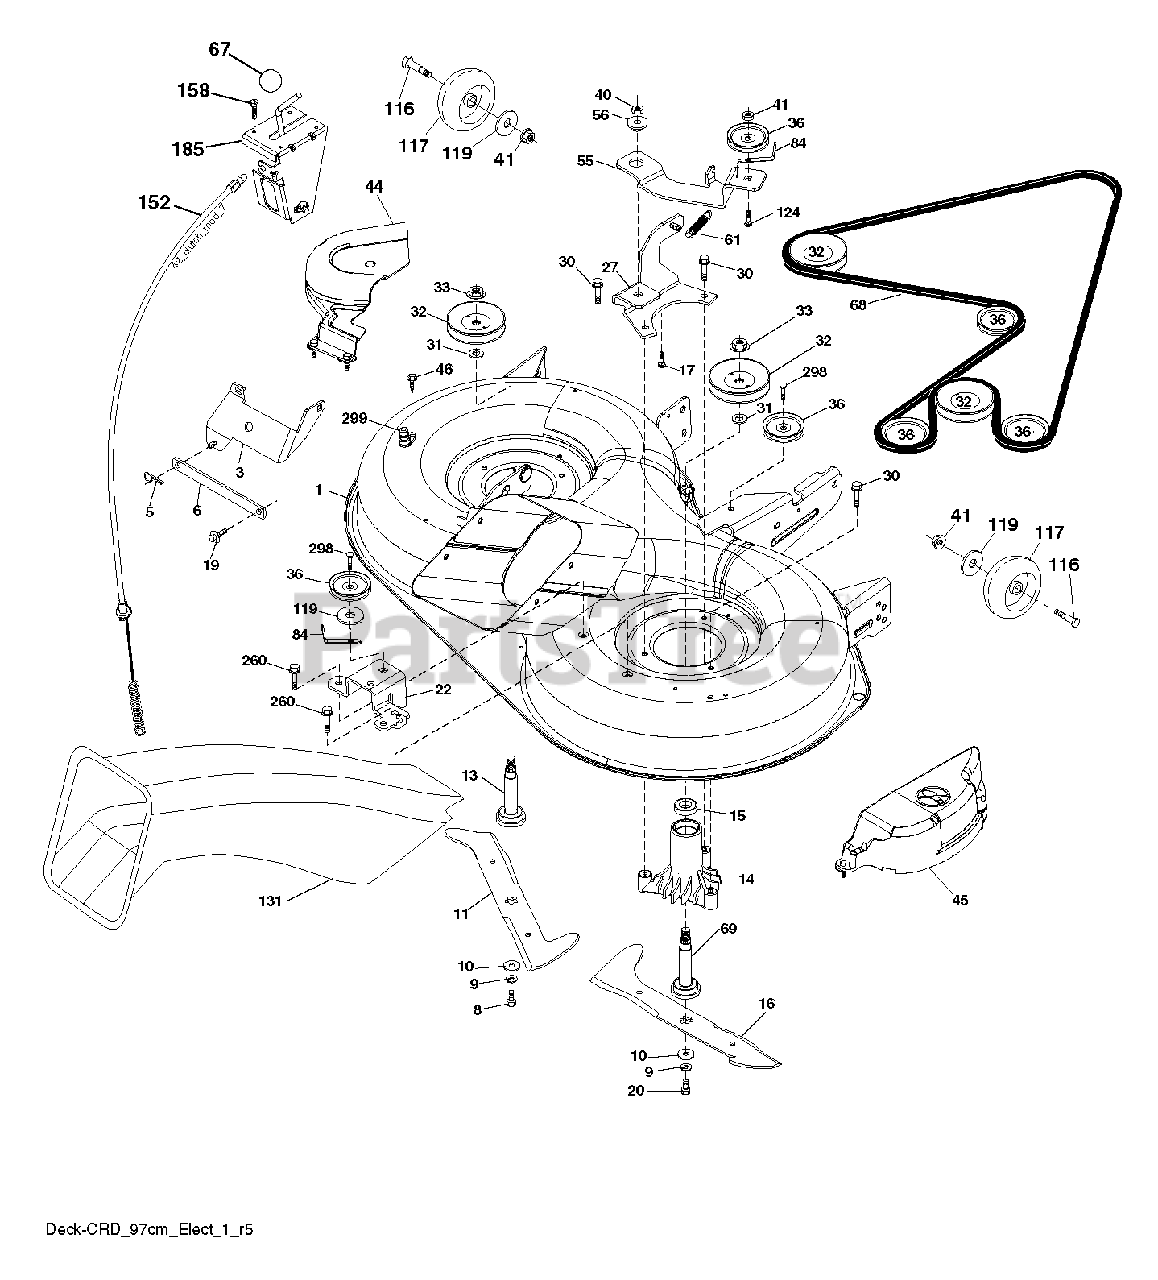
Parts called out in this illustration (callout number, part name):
3	BRACKET.ASM.BAR.SWAY.CHASS
5	RETAINER-SPRNG RB
6	BAR SWAY
9	LOCKWASHER
10	WASHER.BLADE
11	BLADE.3N1.LH.CRD.97
13	SHAFT ASM VENT
14	HSG MANDREL
16	BLADE.3N1.RH.CRD.97
17	BOLT.3/8-14X1.25
19	BOLT SHD 5/16-18
22	BRACKET.SUPT.IDLER.REAR.RH
27	BRACKET.ASM.SUSP.REAR.RH.
30	SCREW, WASHER HEAD
31	WASHER.SPACER.MANDREL
32	PULLEY MANDREL
33	NUT.FLANGE.LOCK.TOP
36	PULLEY.IDLER.4.25
40	LOCKNUT
41	NUT LOCK FLG 3/8-16 UNC
46	SCREW.1/4-20X5/8
56	SPACER.RETAINER.MOWER
67	KNOB T (3/8 HOLE)
68	BELT.DRIVE.CRD.97.2010
69	SHAFT.ASM.W/LWR.BRG.RH.THREAD
84	KEEPER, BELT IDLER
116	BOLT.SHOULDER.3/8-16X3-5/8
117	WHEEL. GUAGE RALLY
124	BOLT.3/8-16X1.50
131	CHUTE BAGGER
158	SCREW
185	HEAD ASM. CABLE CLUTCH
260	SCREW 3/8-16X1/2
298	SCREW LT
299	PORT.WASHOUT
